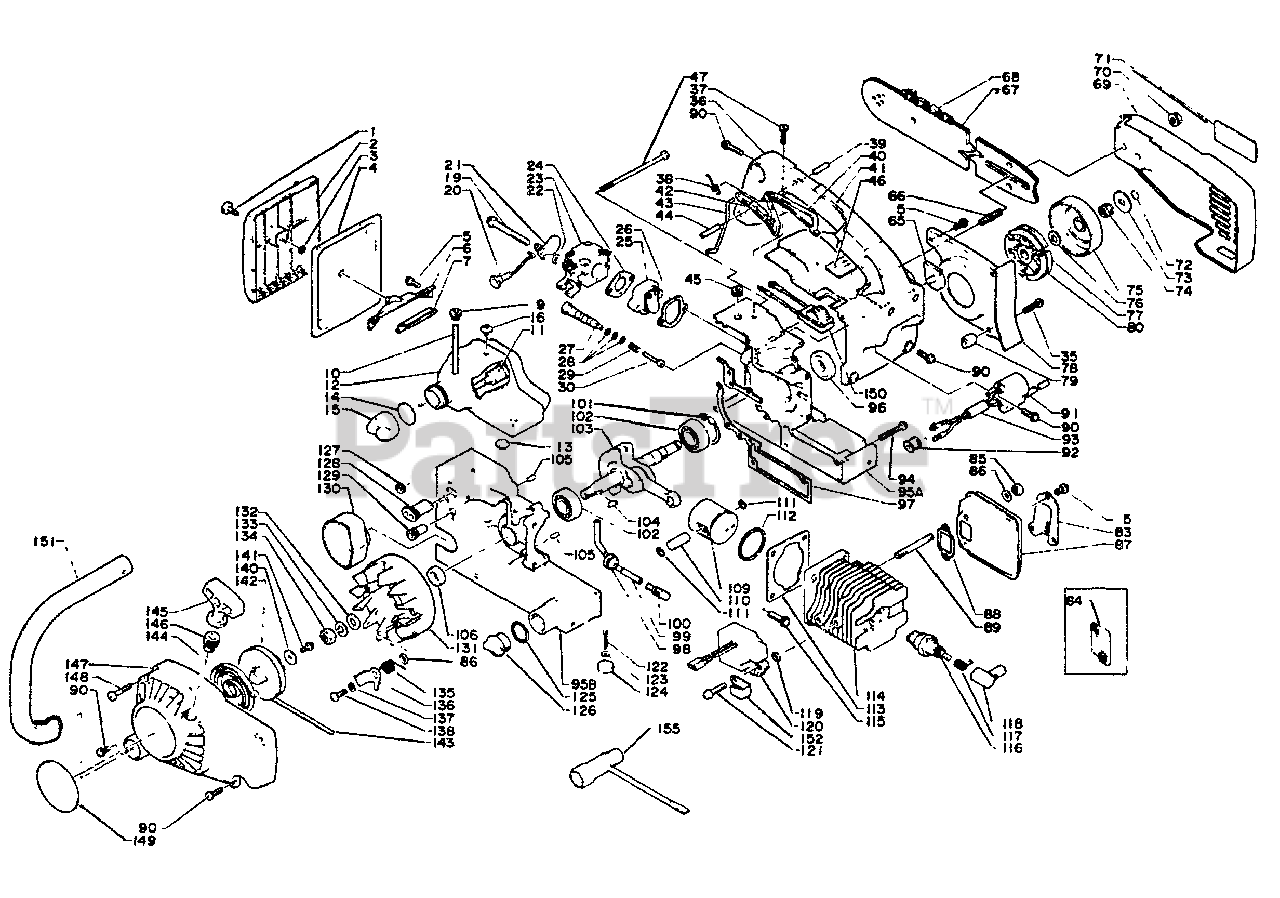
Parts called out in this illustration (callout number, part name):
1	THUMBSCREW
2	COVER, AIR FILTER
3	E-RING 3
4	FILTER, AIR
5	SCREW 4×10
6	BRACKET, AIR FILTER
7	CUSHION
9	GROMMET
10	FUEL PIPE KIT
11	FILTER, FUEL
12	TANK, FUEL
14	GASKET
15	CAP
16	VALVE, CHECK
19	SCREW 5×50
20	ROD, CHOKE
21	SHUTTER, CHOKE
22	WASHER 5.5×8×0.8
23	CARBURETOR
24	GASKET, INTAKE
25	INSULATOR
26	GASKET, INTAKE
27	AUTO-OILER ASSY
30	AUTO-OILER ASSY
35	SCREW 4×20
36	HANDLE - TOP
37	SCREW 4×18
38	SPRING
39	PIN, SPRING 5×18
40	LOCKOUT, THROTTLE
41	GRIP, HANDLE
42	LEVER, THROTTLE
43	ROD, THROTTLE
44	PIN, SPRING 5×25
46	LABEL
65	PLUG
66	BOLT, STUD
67	GUIDE BAR
69	GUARD, SPROCKET
70	NUT - 6 -- FLANGE
71	LABEL - ECHO
72	RING, SNAP
73	WASHER
74	BEARING, NEEDLE 8
75	DRUM, CLUTCH
76	WASHER, CLUTCH
77	CLUTCH ASSY
78	PLATE, SEAL
79	SPACER
80	SPRING, CLUTCH
83	COVER, MUFFLER
84	SCREEN, SPARK ARRESTER
85	LOCKNUT - 5
86	WASHER 5.3×10×1
87	MUFFLER
88	GASKET, EXHAUST
89	BOLT, STUD
90	SCREW 4×16
91	COIL, IGNITION
94	SCREW 4×30
95	CRANKCASE KIT
95A	CRANKCASE KIT
95B	CRANKCASE KIT
96	SEAL, OIL 12
97	GASKET, CRANKCASE
98	GROMMET
99	PIPE, OIL
100	FILTER, OIL
101	RING, SNAP Ø32
102	BEARING, BALL - 6201 C3
103	CRANKSHAFT ASSY
105	PIN, LOCATING 4
106	SEAL, OIL
109	PISTON KIT
110	PIN, PISTON
111	RING, SNAP
112	RING, PISTON
113	GASKET, CYLINDER
114	CYLINDER
115	SCREW - 5×20
116	SPARK PLUG - BPM6A
117	TERMINAL, SPARK PLUG CAP
118	CAP, SPARK PLUG
119	SPACER
120	COIL, IGNITION
121	SCREW 5×22
122	PIN, COTTER
123	WASHER 2 MM
124	PACKING
125	O-RING 16 MM
126	CAP, OIL TANK
127	GROMMET, CHOKE
128	GROMMET
129	GROMMET
130	SEAL
131	FLYWHEEL
132	WASHER 8.5×16×1.2
133	WASHER, SPRING 8
134	NUT 8×1.25
135	SPRING, RETURN
136	RATCHET
137	SPACER 5.2×8×2.1
138	SCREW
140	WASHER 4.1×15.5×1T
141	SCREW - 4×10
142	REEL, ROPE
143	ROPE, STARTER 3.0×850
144	SPRING, RECOIL
146	GUIDE, ROPE
147	COVER, FAN
148	SCREW 4×25
149	LABEL, ECHO
150	IGNITION SWITCH ASSY
151	HANDLE, FRONT
152	CLAMP
155	WRENCH W/S, DRIVER
